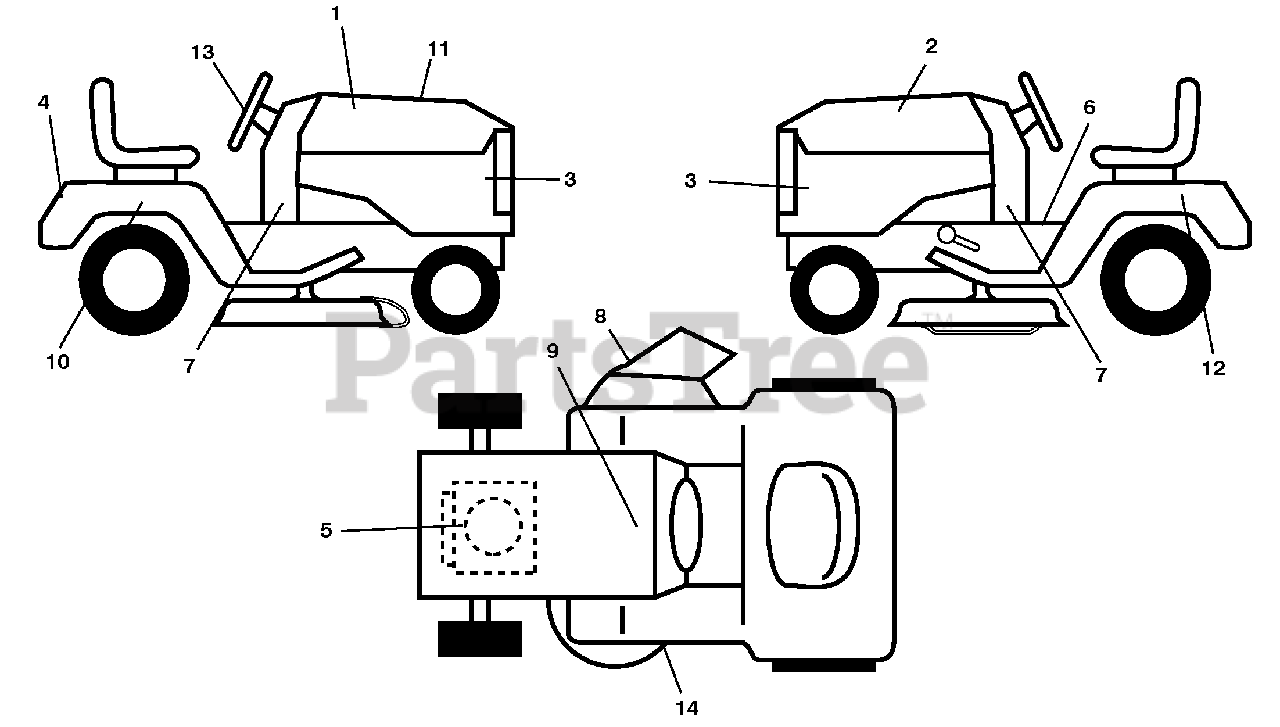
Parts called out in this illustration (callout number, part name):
1	Decal, Hood RH
2	Decal, Hood LH
3	Decal, Side Panel
4	Decal, Fender
5	Decal, Engine
6	Decal, Fender Operator's
7	Decal, Lower Dash
8	Decal, Warning
9	Decal, Battery Dan./Poi.
10	Decal, Fender Side LH
11	Decal, Replacement
12	Decal, Fender Side RH
13	Decal, Steering Wheel
14	Decal, Mower Schematic
14	Pad, Footrest, RH
14	Decal, Bypass
14	Pad, Footrest, LH
14	Manual, Operator's (Eng./French)
14	Manual, Parts (Eng./French)
